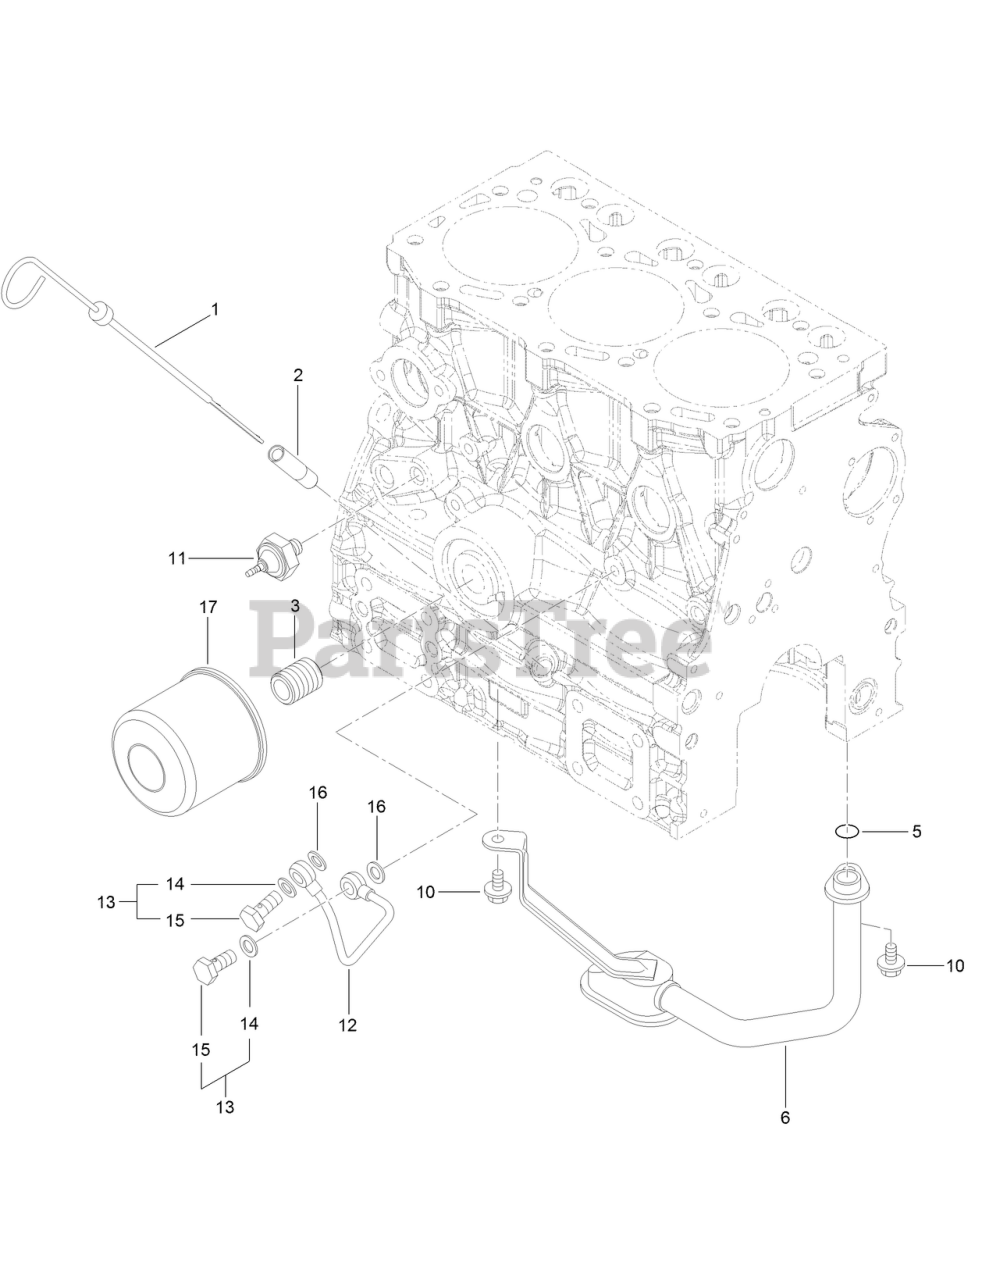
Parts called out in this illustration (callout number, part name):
1	DIPSTICK
2	GUIDE-DIPSTICK
5	O-RING
6	OIL INLET PIPE ASM
11	SWITCH-HYDRAULIC
12	PIPE-OIL
13	JOINT BOLT ASM
14	WASHER-SEAL
15	BOLT-JOINT
16	WASHER-SEAL
17	FILTER ENGINE OIL
